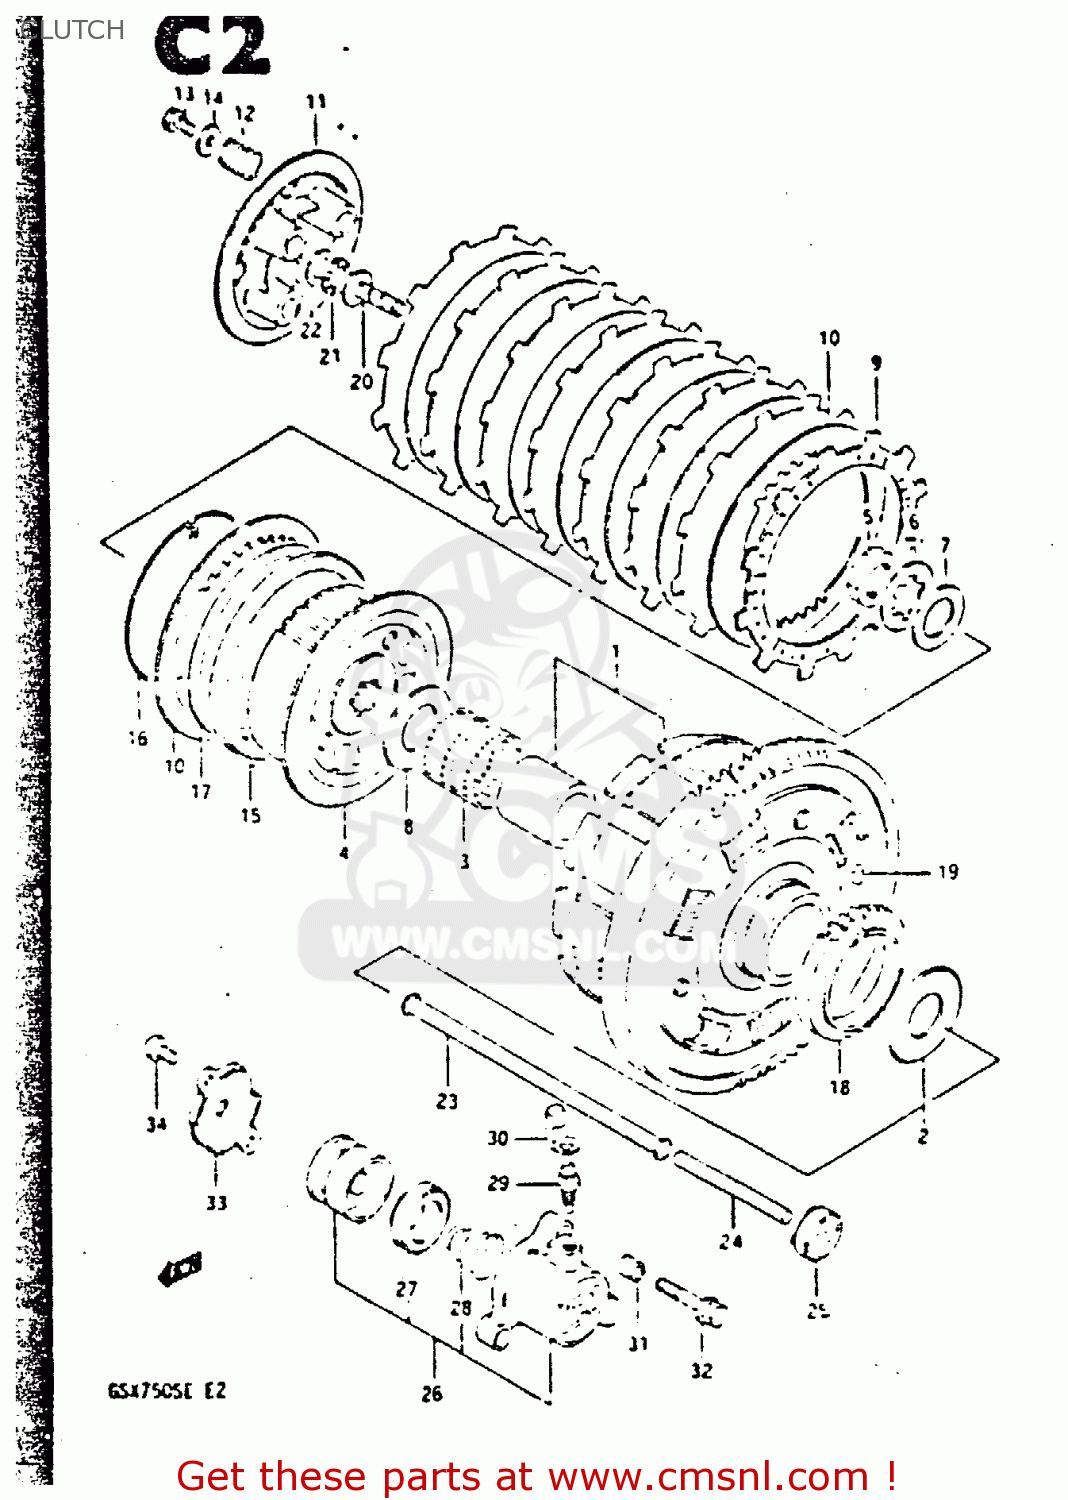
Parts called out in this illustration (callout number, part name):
1	GEAR, PRIMARY DRIVEN (NT:91)
2	WASHER(25X54X2.5)
3	BEARING(35X40X39.8)
4	HUB,CLUTCH SLEEVE
5	NUT
6	WASHER,LOCK
7	WASHER
8	WASHER(25X50X2.5)
9	PLATE,CLUTCH DRIVE (MCA)
10	PLATE,CLUTCH DRIVEN(T:2.0) (NAS)
11	PLATE,CLUTCH PRESSURE
12	SPRING
13	BOLT, UPPER
14	WASHER
15	SEAT,WAVE WASHER
16	RING,STOPPER
17	WASHER
18	GEAR,OIL PUMP DRIVE
19	PIN(6X6)
20	PIECE,CLUTCH PUSH
21	BEARING(15X28X2)
22	WASHER
23	ROD,CLUTCH PUSH
24	ROD,CLUTCH PUSH,L
25	SEAL,OIL(6X34X7.5)
26	CYLINDER,CLUTCH RELEASE
27	CUP,CLUTCH CYLINDER
28	SPRING,CLUTCH CYLINDER
29	BLEEDER
30	CAP,BLEEDER
31	PIN
32	BOLT 6X30
33	COVER, CYLINDER
34	SCREW
